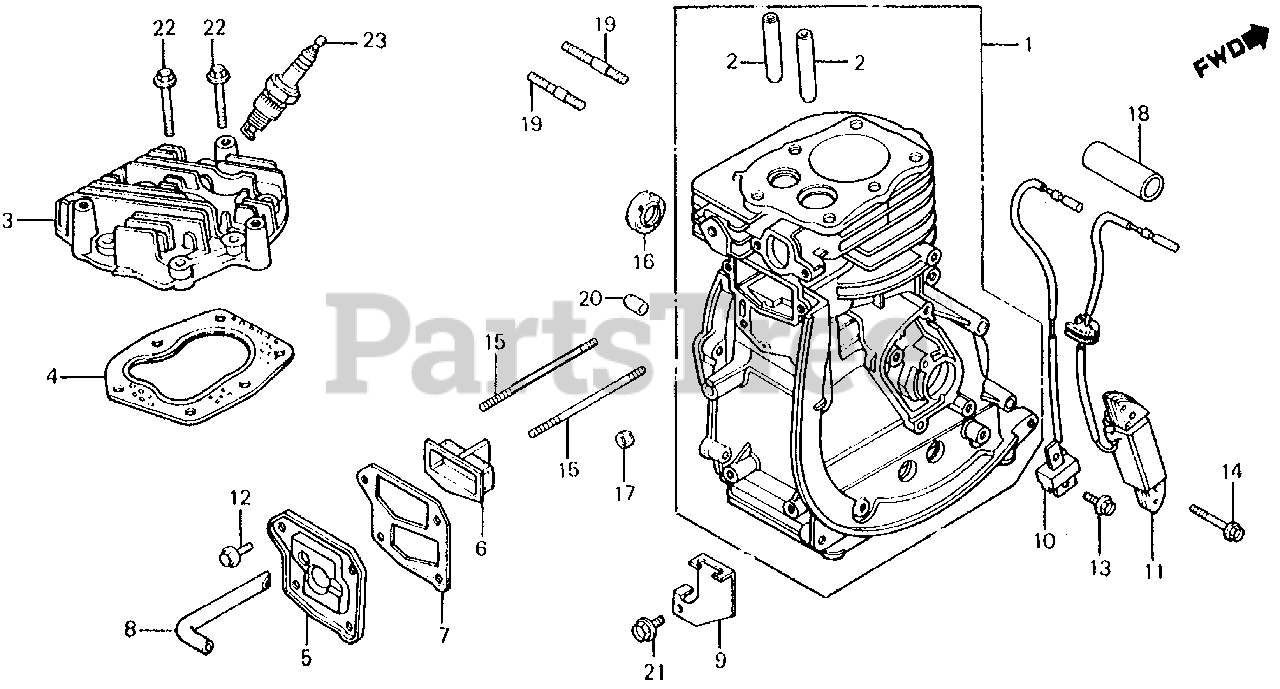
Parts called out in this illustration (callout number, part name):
2	GUIDE, VALVE
3	CYLINDER HEAD
4	GASKET, CYLINDER HEAD
5	COVER, TAPPET (NOT AVAILABLE)
6	SEPARATOR (INNER)
7	GASKET, TAPPET COVER
8	TUBE, BREATHER
9	HOLDER, TUBE
10	COIL, PULSER
11	COIL, EXCITER
12	BOLT, FLANGE (5X10)
13	BOLT, FLANGE (5X12)
14	BOLT, FLANGE (5X25)
15	BOLT, STUD (5X80)
16	OIL SEAL (17X30X6) (NOK)
18	TUBE, CORD
19	BOLT, STUD (6X28)
20	PIN A, DOWEL (8X14)
21	BOLT, FLANGE (6X10)
22	BOLT, FLANGE (6X35)
23	SPARK PLUG (BPR-4HS-10) (NGK)
23	SPARK PLUG (BPR4HS-10) (NGK)
23	SPARK PLUG (W14FPR-UL10) (DENSO)
